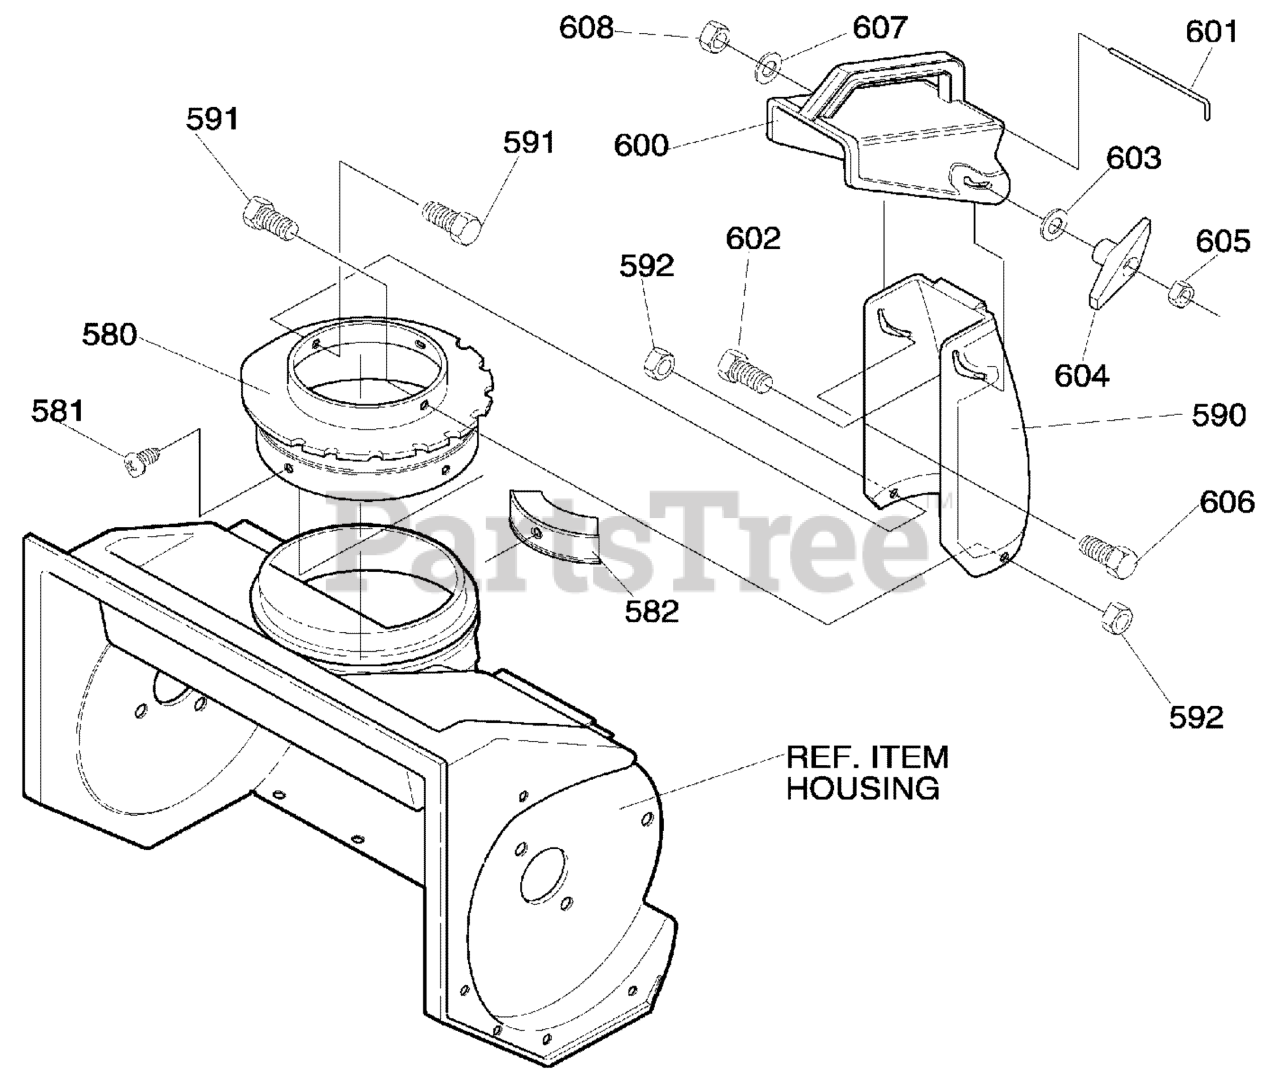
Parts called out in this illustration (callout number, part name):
580	RING, CHUTE
581	SCREW, 1/4-20 x .50
582	GUIDE, CHUTE
590	LOWER CHUTE
591	SCREW, 1/4-20 x .50
592	NUT, 1/4-20
600	UPPER CHUTE
601	WIRE HINGE
602	BOLT, 5/16-18 x 1.25
603	FLATWASHER
604	T KNOB
605	NUT, 5/16-18
606	SCREW, 5/16-18 x 0.75 SL
607	FLATWASHER
608	NUT, 5/16-18
